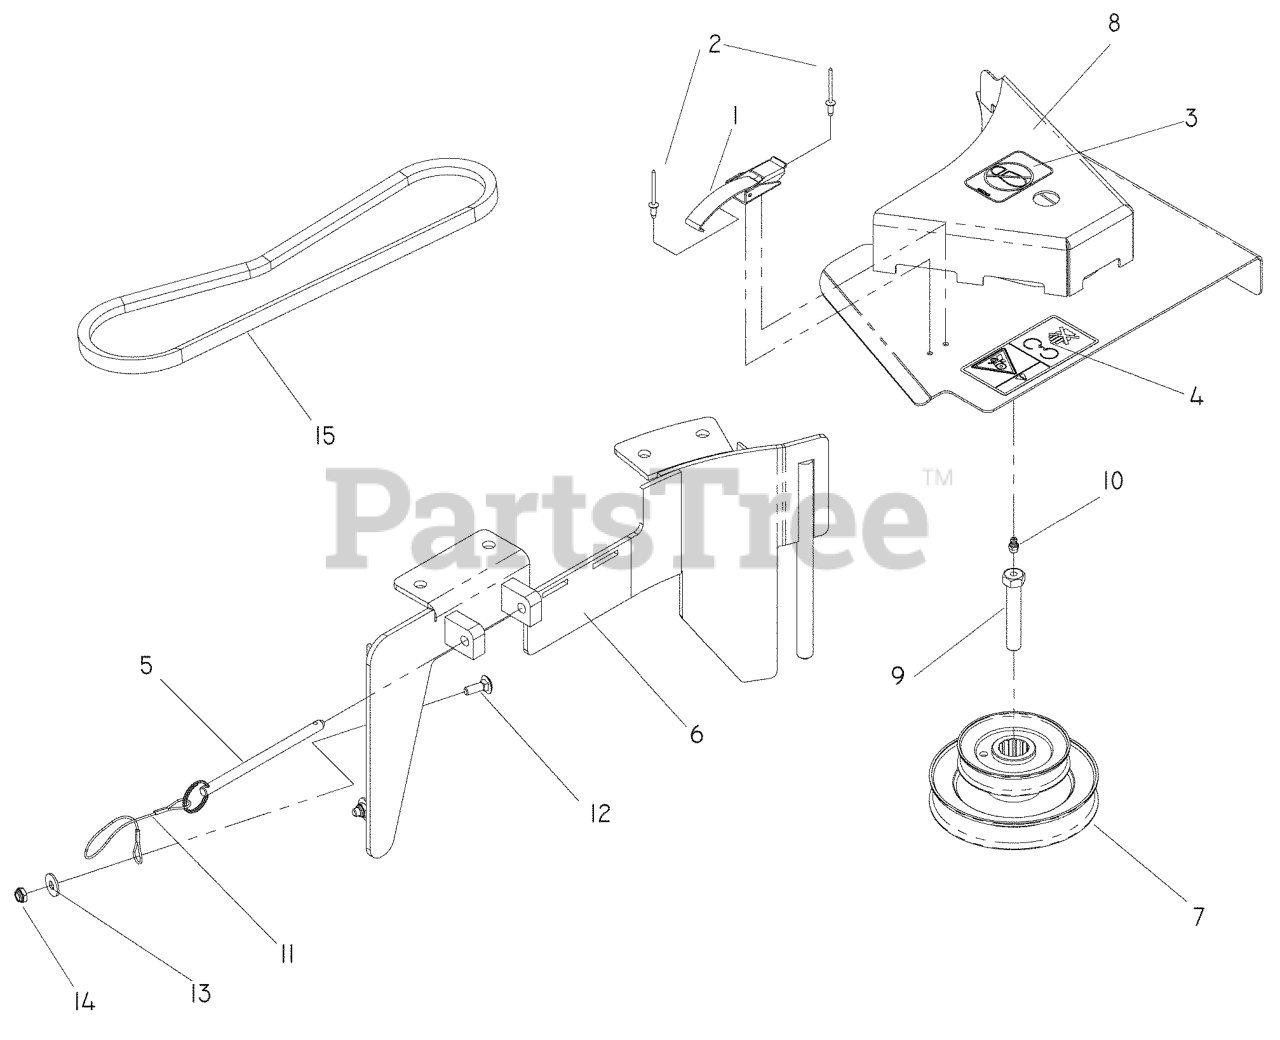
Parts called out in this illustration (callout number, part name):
1	DRAW LATCH
2	RIVET, BLIND, 5/32 DIA
3	DECAL, NO STEP
4	DECAL, BELT DRIVE
6	BLOWER DECK PLATE WLDMT, 52
7	52 LNG DOUBLE HEX STACK PULLEY
8	BELT SHIELD ASSY 52"
9	HCS, 7/16-20 X 2 1/2, GR8
10	ZERK
12	RHSNB 1/4C X 3/4
13	WASHER 1/4 FLAT
14	JAM NUT 1/4C (2 2 PW01)
